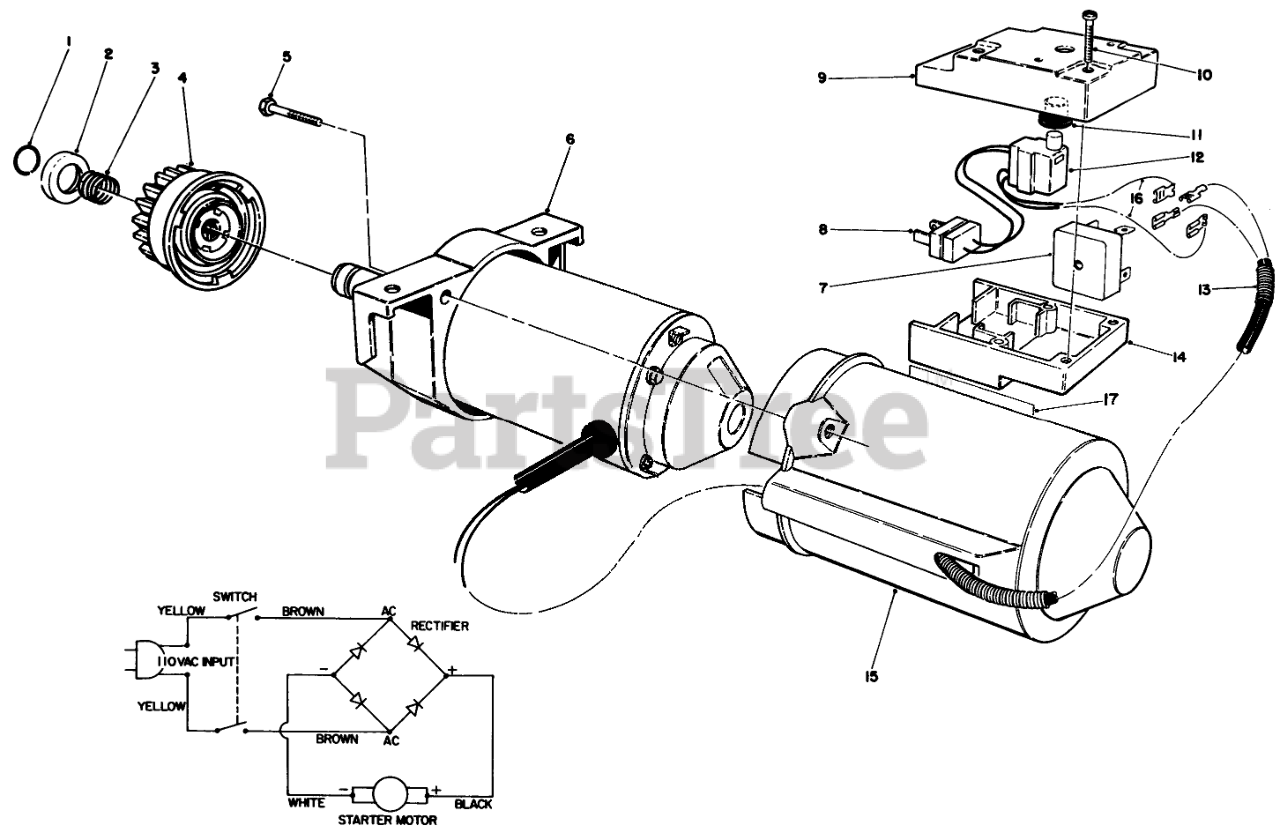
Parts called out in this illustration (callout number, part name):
1	RING-LOCK
2	PINION STOP
3	SPRING
4	Pinion ASM
5	Screw-Plastite
6	Starter Motor Assembly (Incl. Ref. #1-4)(Model No. 38185 only)
6	Starter Motor Assembly (Incl. Ref. #1-4)(Model No. 38185C only)
7	RECTIFIER-BRIDGE
8	Plug
9	Cap-Switch Housing
9	SWITCH BOX CAP
10	SCREW
11	BOOT-SWITCH
12	SWITCH-STARTER
13	CABLE COVER
14	Linkage-Choke
14	SWITCH BOX BASE
15	STARTER MOTOR COVER
17	Decal-UL (Model No. 38185)
17	Decal-CSA (Model No. 38185C)
